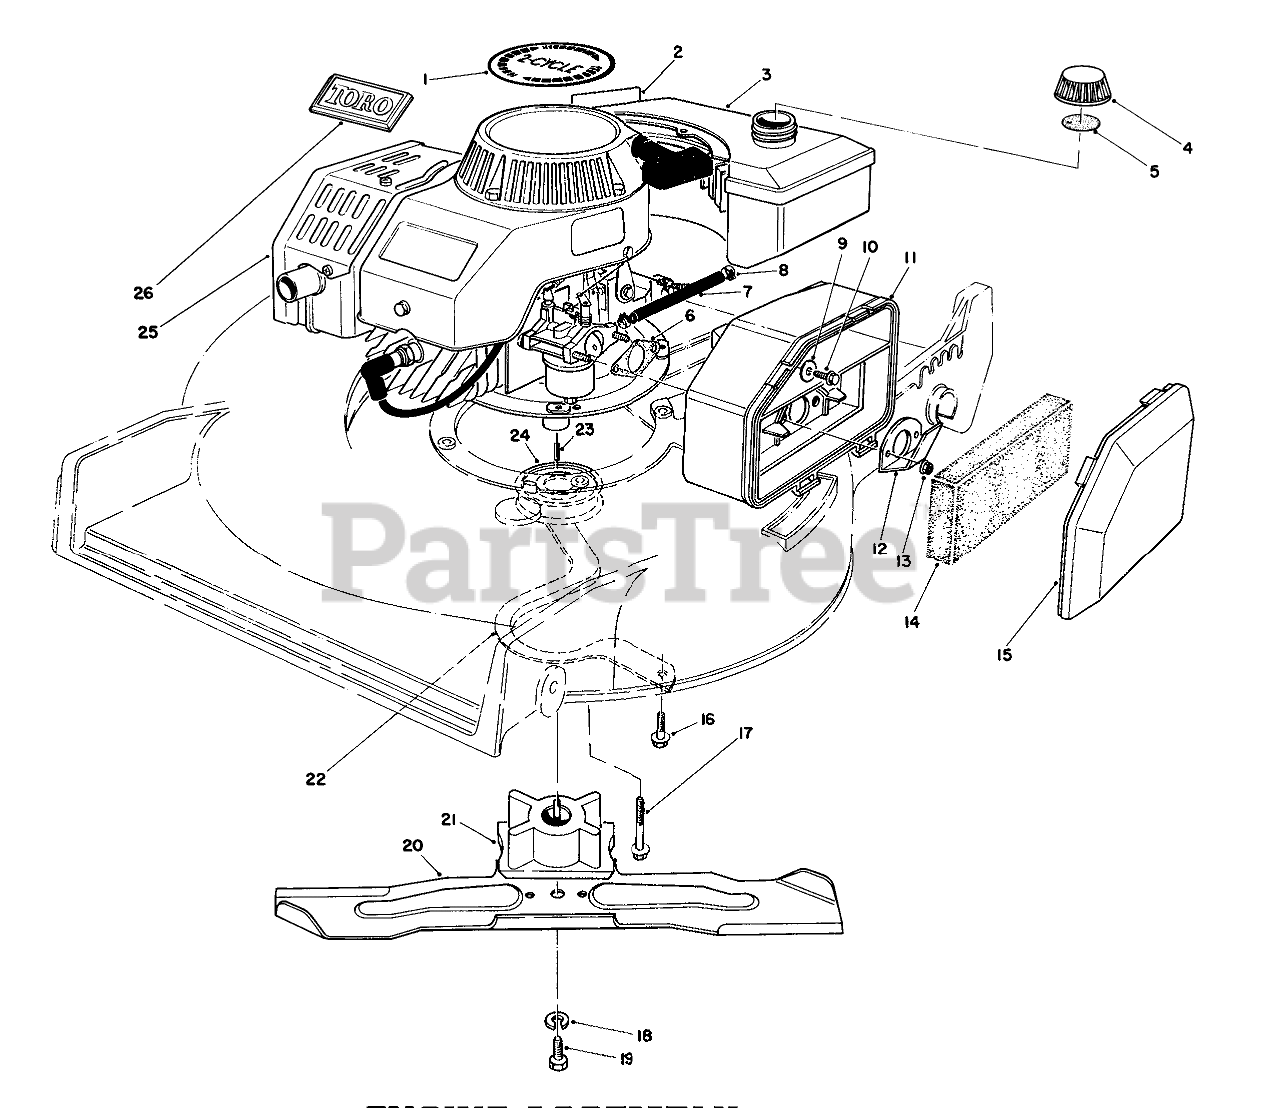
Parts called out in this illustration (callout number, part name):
1	DECAL- 2 CYC RECOIL
2	Decal-Maintenance
3	Gas Tank Assembly
4	Gas Cap Assembly (Incl. Ref. #5)
5	GAS CAP GASKET
6	GASKET-AIR CLEANER
7	FUEL LINE
8	CLAMP-HOSE
9	WASHER-FLAT
10	SCREW-HH
11	AIR CLEANER
12	SPIT BACK DEFLECTOR
13	NUT-LOCK
14	FILTER
15	AIR CLEANER COVER
16	Screw
17	SCREW-HHF
18	WASHER-LOCK
19	SCREW-BLADE
20	BLADE-21in
21	Retainer Blade
22	BELT GUIDE
23	KEY-SQUARE
24	PULLEY-DRIVER
25	Engine
26	TORO LOGO PLT
